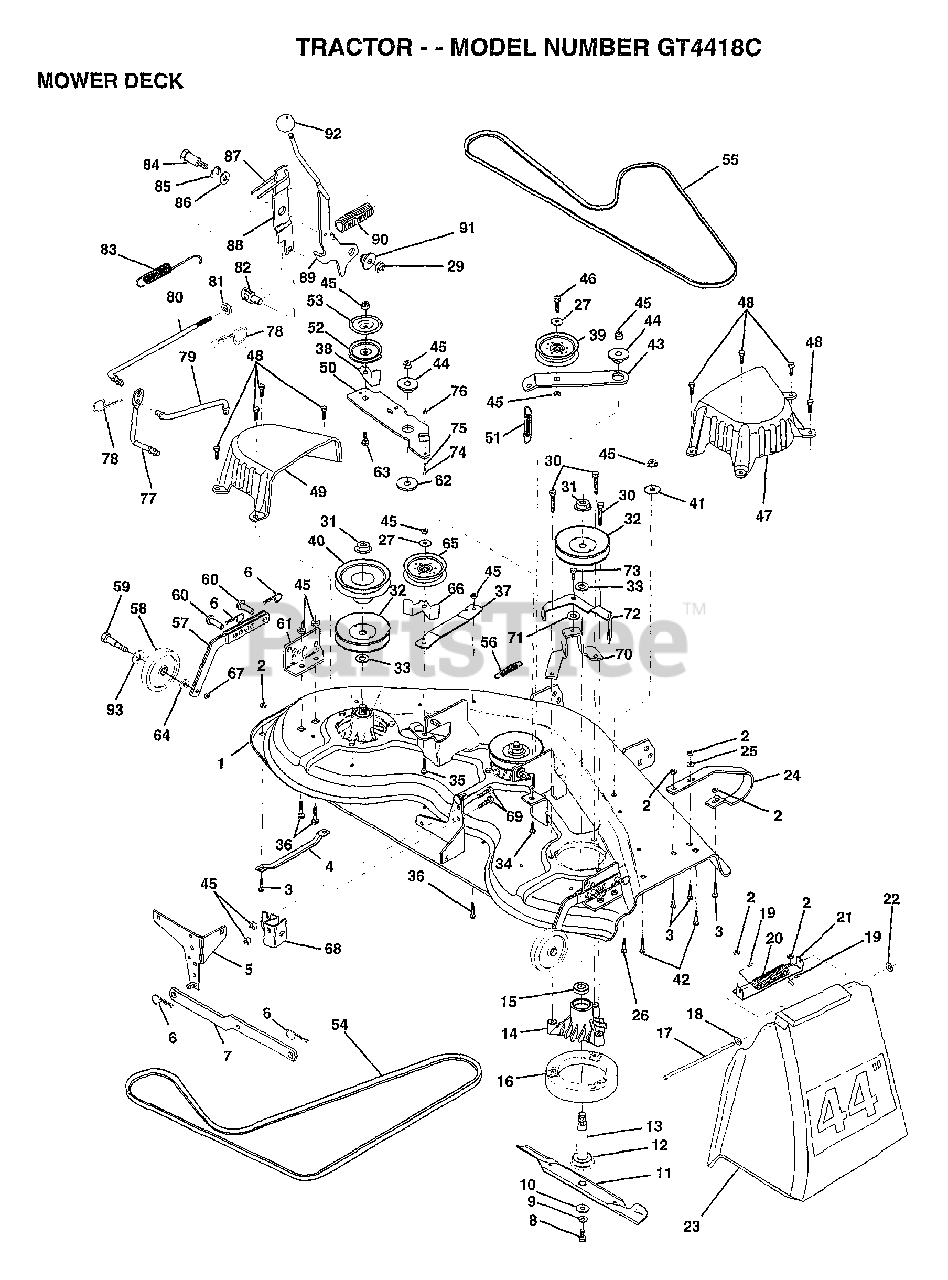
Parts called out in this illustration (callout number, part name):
1	"DECK ASM WELD44"""
4	RUNNER-LH M
5	BRKT.ASM.SW.44/50
8	BLADE BOLT
10	WASHER.HARD.BLADE
11	"BLADE.44"" HIPERF"
12	BEARING.BALL
13	SHAFT.ASM.W/BRNG
14	HOUSING.MAND.44.V
15	BEARING
16	STRIPPER RND MWR
17	ROD-HINGE T
18	WASHER
19	CAP-SLEEVE LT
20	SPRING TORSION
21	BRKT DEFLECTOR
22	NUT PUSH M
23	DEFLECTOR SHIELD
24	RUNNER.RH
25	WASHER M
26	BOLT
27	WASHER
33	WASHER
34	BOLT.3/8-14X1.25
35	BOLT
36	BOLT D
37	STIFFENER.ARM.IDL
38	KEEPER BELT IDLER
39	FLAT IDLER PULLEY
40	"PULLEY.DRIVEN.44"""
42	BOLT
43	"ARM.IDLER.SEC.44"""
44	SPACER RETAINER
47	"COVER.MAND.RH.44"""
48	SCREW.1/4-20X5/8
49	COVER.MANDREL.LH
50	ARM.IDLER.PRIMARY
51	"SPRING.SEC.44""VEN"
52	PULLEY.IDLER.VGRO
53	SHIELD.IDLER.44.V
54	BELT-V MOWER PRIM
55	BELT-V.88.12.MW
56	"SPRING,EXTENTION"
57	BAR.ASM.GUAGE.WHL
58	WHEEL.GAGE.BLK.PL
59	BOLT M
60	PIN.CLEVIS
61	BRACKET.GUAGE.WHL
62	HARDENED WASHER
63	BOLT.3/8-16X1.50
64	WASHER
65	IDLER-FLAT T
67	LOCKNUT
68	BRACKET PVT MCH
70	"BRACKET SUPT 44"""
71	HARD SMALL WASHER
72	ARM BRAKE ASM
73	BOLT.SHLD.5/16-18
75	SHOULDER BOLT
76	LOCKNUT
77	PIVOT ROD
78	RETAINER M
79	ROD CLUTCH SECON
80	ROD.CLUTCH.PRIM44
81	NUT
82	TRUNION ADJ
83	SPRING.EXT.RETURN
84	SHOULDER BOLT
85	RING
86	WASHER
87	SPRING KEEPER
88	CLUTCH ARM SECOND
91	BUSHING
92	KNOB T (1/2-HOLE)
93	WASHER
